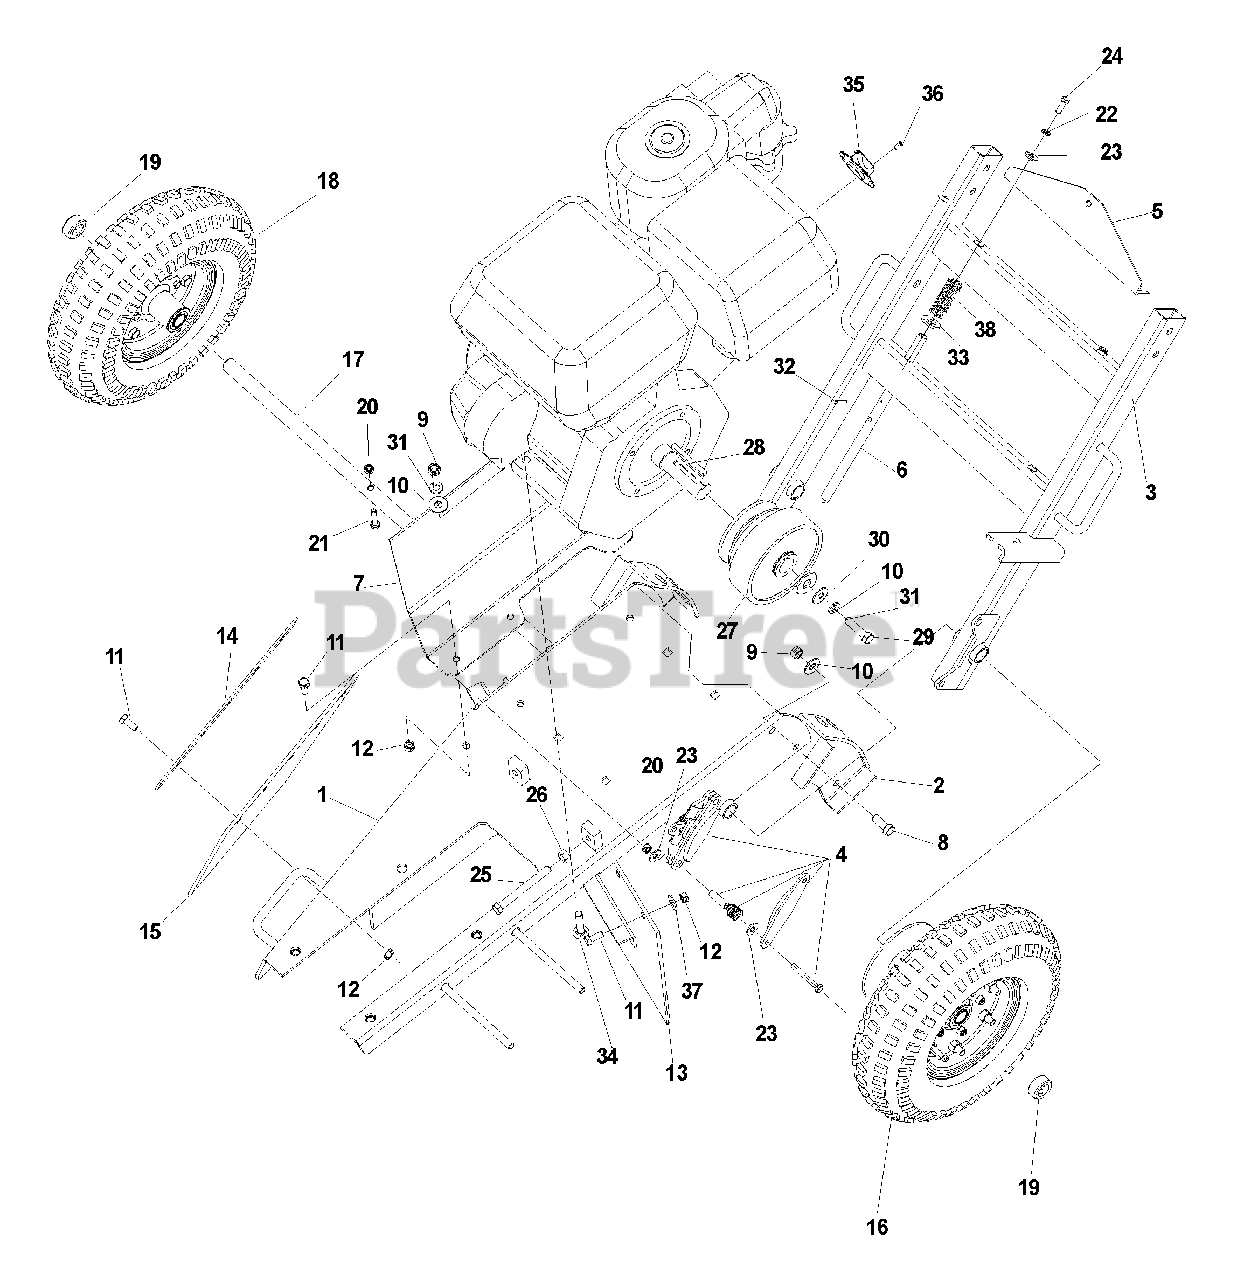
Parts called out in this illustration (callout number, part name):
2	BRACKET, KIT
3	HANDLE, LOWER
4	BRAKE, CALIPER
5	BRACKET, HANDLE POSTIONING
6	PIN, HANDLE ADJUSTMENT
8	HCS 3/8-16 X 1, GR5
9	NUT 3/8-16, CENTER LOCK
10	WASHER, 3/8, FLAT
11	HCS 5/16-18 X 3/4, GR5
12	NUT 5/16-18, CENTER LOCK
13	DEFLECTOR, NEOPRENE, REAR
14	STRAP, DEFLECTOR
15	DEFLECTOR, SIDE, NEOPRENE
16	WHEEL W/DISC, 12" SNOW HOG
17	AXLE
18	WHEEL, 12" SNOW HOG
19	SET COLLAR, 3/4" BORE
20	NUT 1/4-20, CENTER LOCK
21	HCS 1/4-20 X 1 1/4, GR5
22	LOCKWASHER, 1/4
23	WASHER, 1/4, FLAT
24	HCS 1/4-20 X 3/4, GR5
25	HCS 3/8-16 X 3 1/2, GR5
26	NUT 3/8-16
27	CLUTCH, CENTRIFUGAL, 2-GROOVE
28	KEY, 1/4 SQ X 2 1/2"
29	HCS 3/8-24 X 1 1/2, GR5
30	WASHER 1/2, FLAT
31	LOCK WASHER, 3/8
32	COTTER PIN
33	WASHER 1/2, SAE FLAT
34	RHSNB 3/8-16 X 1 3/4, GR5
35	DEFLECTOR, EXHAUST
36	SCREW #8-32 X 3/8, SELF TAP, PHIL
37	WASHER 5/16, FLAT
38	SPRING, COMPRESSION
